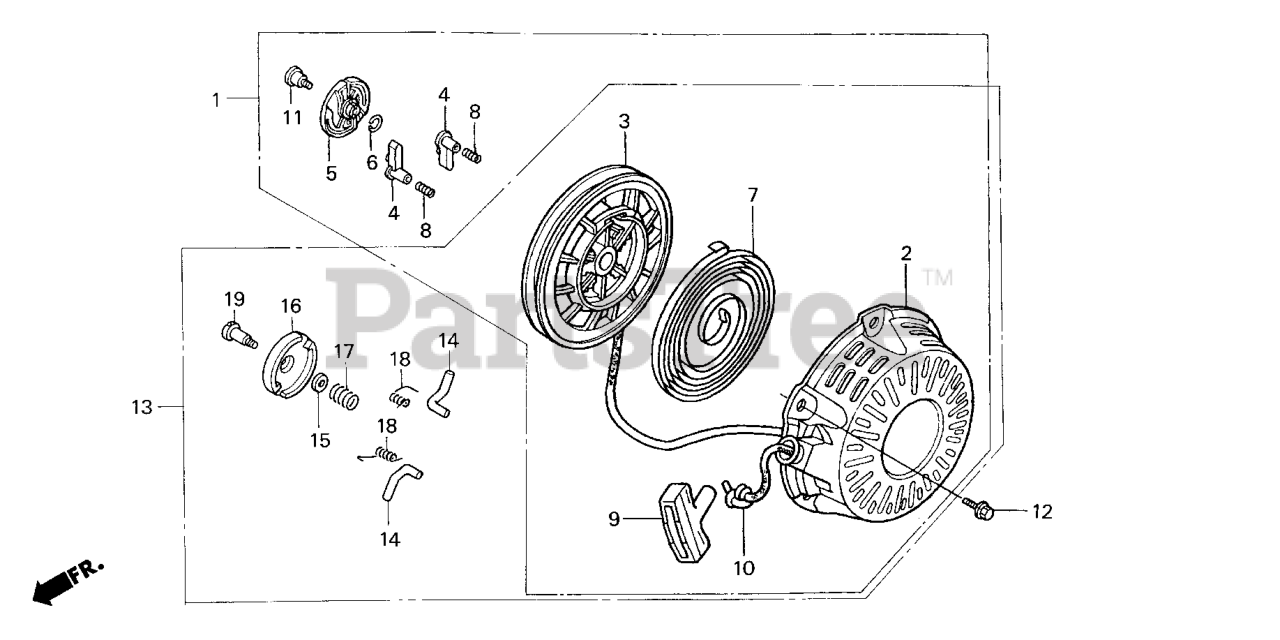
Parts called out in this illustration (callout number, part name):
1	STARTER ASSY., RECOIL *R280* (POWER RED)
2	CASE, RECOIL STARTER *R280* (Honda Code 7346836). (POWER RED)
3	REEL, RECOIL STARTER (NATURAL) (ENGINE NO.)
4	RATCHET, STARTER
5	GUIDE, RATCHET (ENGINE NO.)
6	SPRING, FRICTION (ENGINE NO.)
7	SPRING, RECOIL STARTER
8	SPRING, RETURN (ENGINE NO.)
9	GRIP, STARTER
10	ROPE, RECOIL STARTER (#5X55")
11	SCREW, SETTING (ENGINE NO.)
12	BOLT, FLANGE (6X8)
